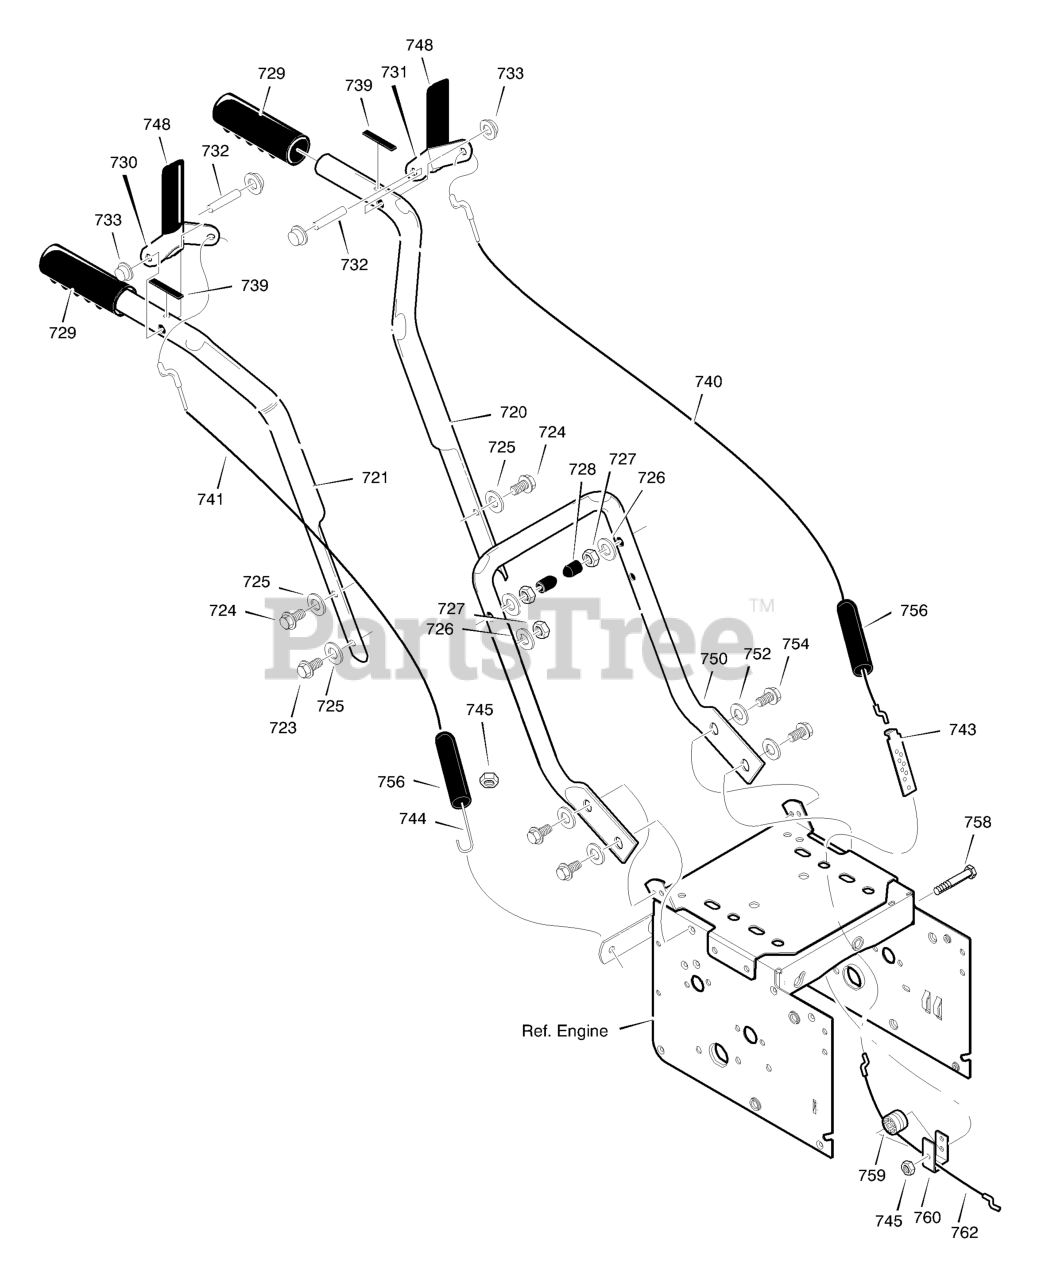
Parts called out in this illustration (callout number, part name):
720	HANDLE, UPPER LH
721	HANDLE, UPPER RH
723	SCREW, 3/8-16 X 2.00
724	SCREW, 3/8-16 x 3.00
725	WASHER, FLAT
726	WASHER
727	NUT, 3/8-16 REGHEX
728	STOP, PLASTIC
729	GRIP-HANDLE FINGER
730	LEVER, ASSY CLUTCH DRIVE RH
731	LEVER, ASSY CLUTCH DRIVE LH
732	PIN, PIVOT CLUTCH
733	NUT, PUSH ON CAP
739	BUMPER, RECTANGLE
740	CABLE, AUGER DRIVE
741	CABLE, AUGER CLUTCH
743	BRACKET, CABLE ADJUSTER
744	SPRING, AUGER CLUTCH
745	NUT, 1/4-20
750	HANDLE, LOWER
752	WASHER, SPTLK
754	SCREW, TAP 5/16-18 X 0.75
756	BOOT, CABLE
758	BOLT, HEX 1/4-20 X 1.50 YZ
759	SPOOL-CABLE, AUGRT CLUTCH
760	BRACKET, CABLE SPOOL YZ
762	CABLE, LOWER DRIVE 12"
